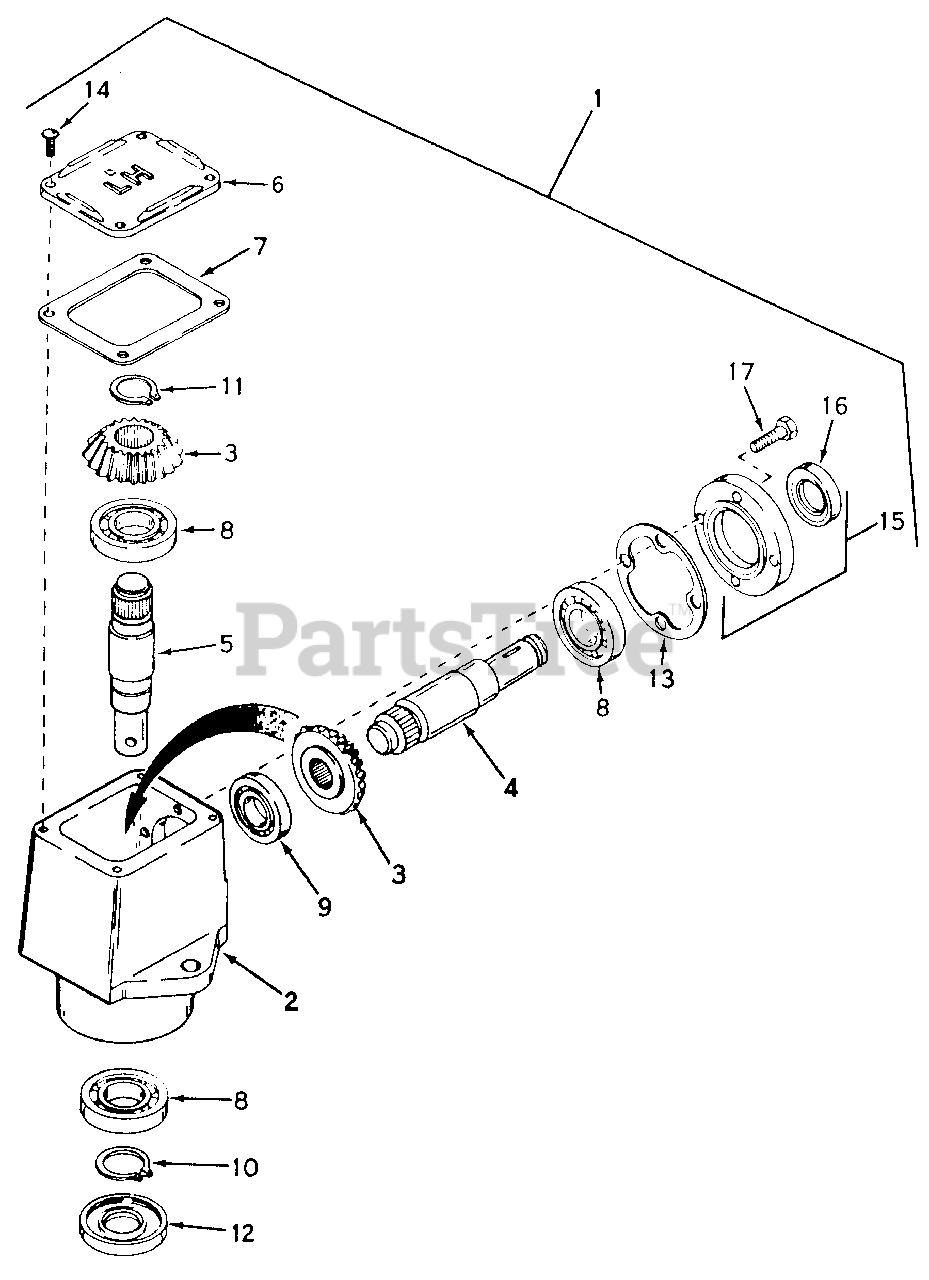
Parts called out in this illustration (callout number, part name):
1	Drive, Right Angle
2	Housing, Right Angle Drive
3	Gear, Miter
4	Shaft, Input
5	Shaft, Output
6	Cover, Housing
7	Gasket, Cover
8	Bearing Assy, Ball
9	Bearing Assy, Ball
10	Ring, Snap
11	Ring, Snap
12	Seal, Oil
13	Gasket, Cap
14	Screw, 10-24 X 1/2 Rd Hd Self-Tapping
15	Cap & Seal Assy, Retainer
17	Bolt, 1/4 X 7/8 Type 5
